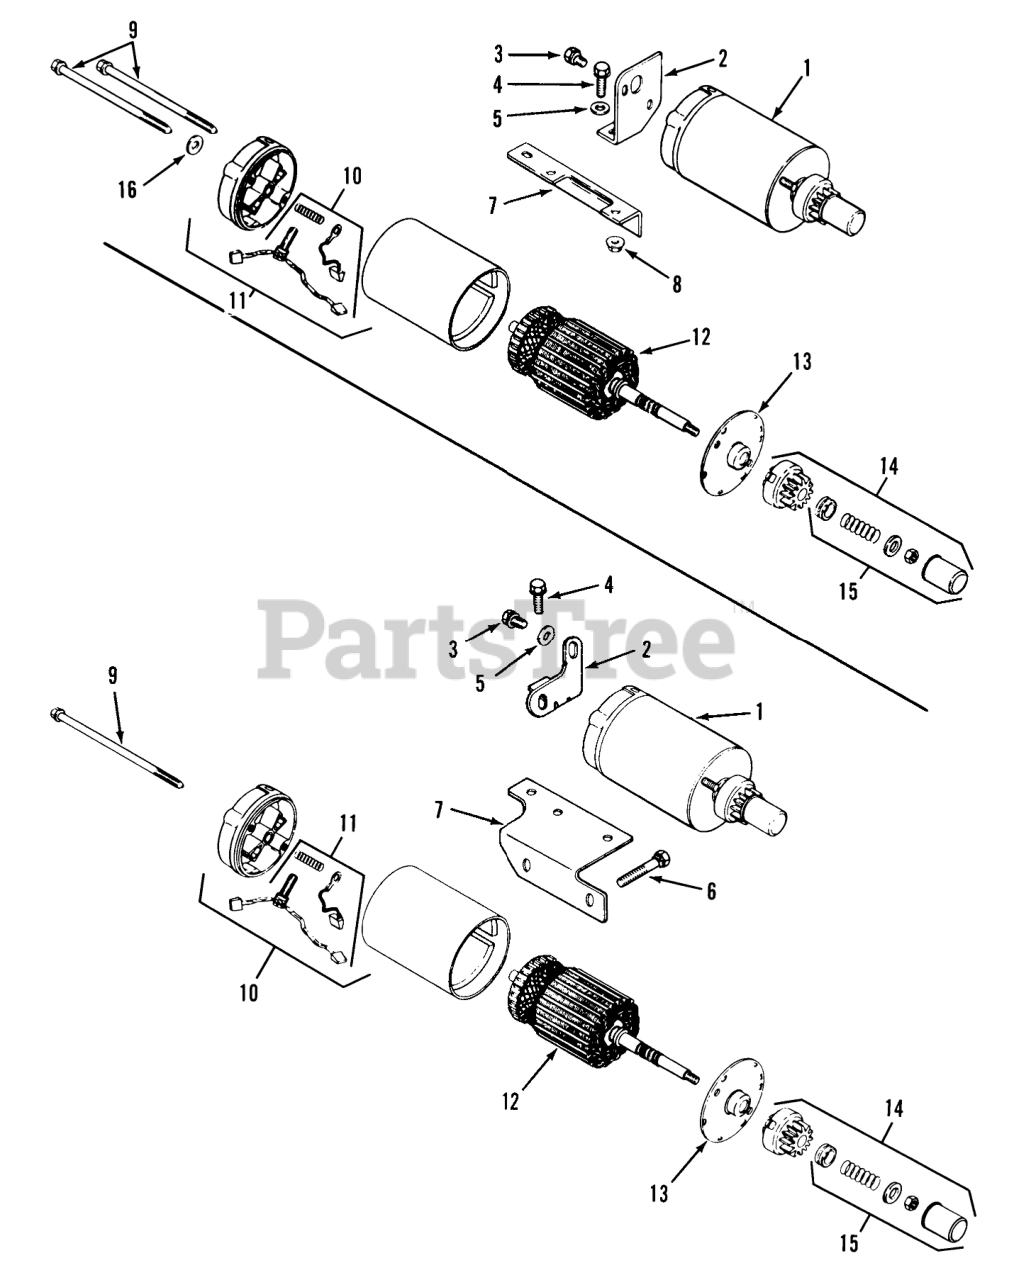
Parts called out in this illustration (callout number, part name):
1	Starter Assy (includes items 9 thru 15)
2	Starter Tail Brace 308 Only
3	Screw-Hex. Hd.
4	Washer-Lock
5	Washer
6	Screw
7	Starter Bracket 308 Only
8	Palnut
10	Commutator End Cap Assembly (includes item 11)
11	Brush Kit
12	Armature
13	Cap-Drive End
14	Drive Kit (includes item 15)
15	Drive Parts Kit
16	Washer
